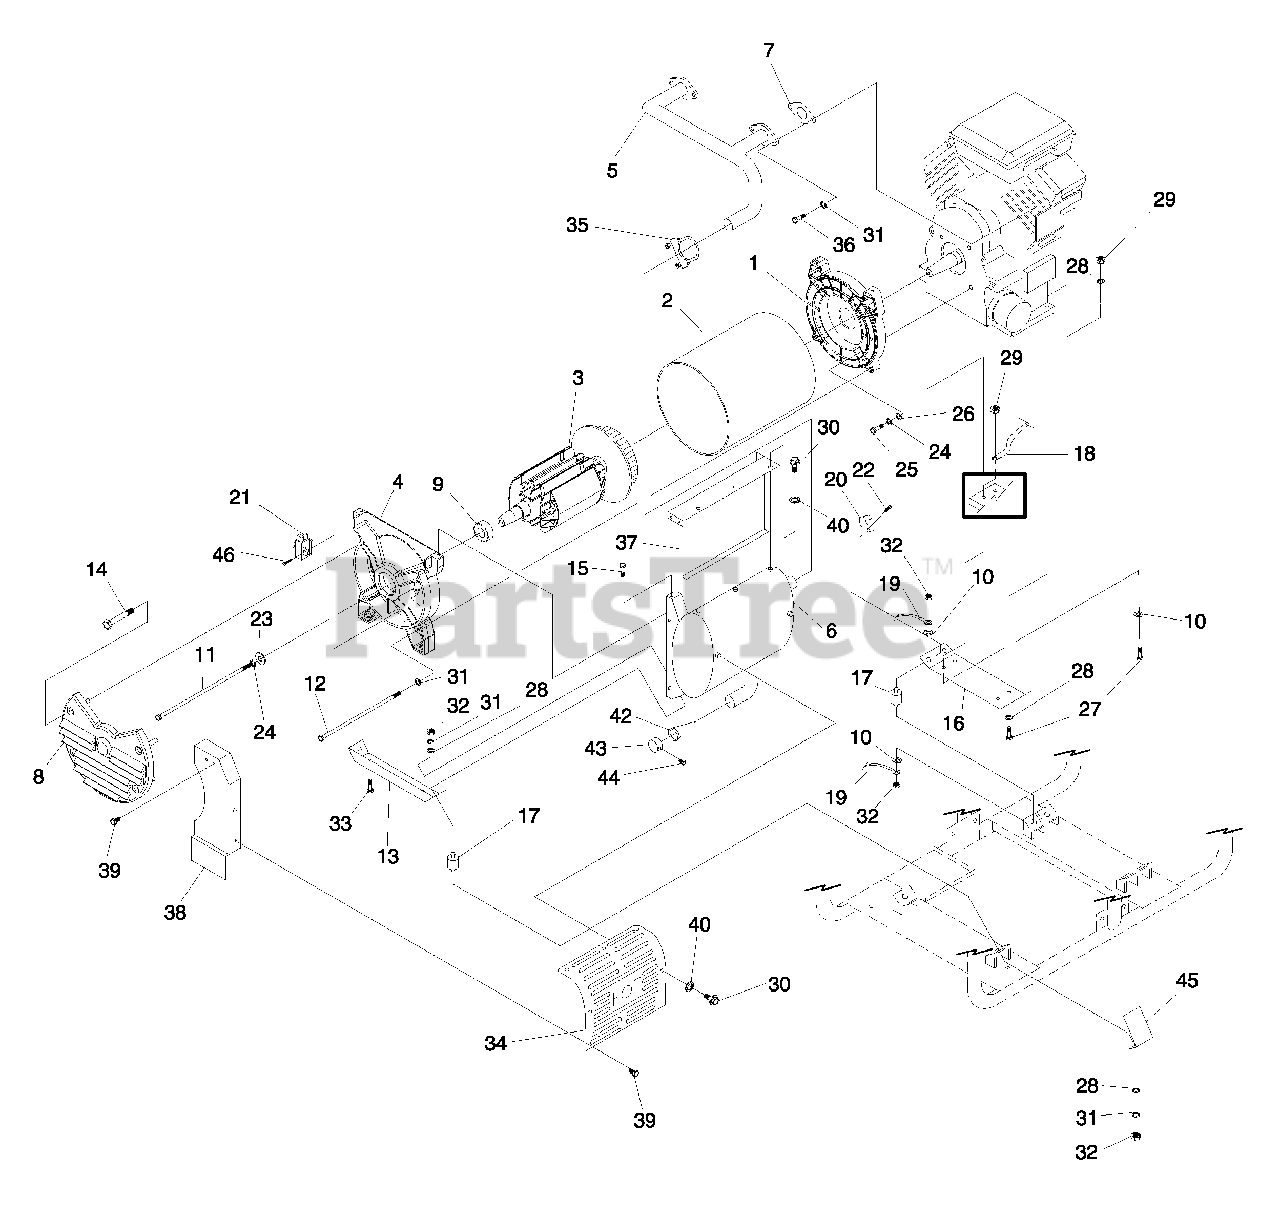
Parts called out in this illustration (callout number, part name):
1	ADAPTOR, ENGINE
2	STATOR 12.5KW
3	ASSEMBLY, ROTOR WITH FAN 12.5KW
4	CARRIER, REAR BEARING
5	EXHAUST MANIFOLD
6	MUFFLER
7	GASKET, EXHAUST
8	COVER, ALTERNATOR AIR IN
9	BEARING
10	5/16 SPECIAL LOCK WASHER
11	SCREW IHHC 3/8-24 X 15.50 G5
12	SCREW IHHC M8-1.25 X 400 G8.8
13	BRACKET, ALT MOUNTING
14	SCREW HHTT #10-32 X 1.75
15	SCREW HHTT M8-1.2 X 20
16	ENGINE MOUNTING PLATE
17	RUBBER MOUNT
18	BATTERY CABLE, BLACK
19	EARTH STRAP 3/8X 3/8
20	CLIP-J VINYL COAT .625 ID
21	ASSEMBLY, BRUSH HOLDER
22	SCREW TAP-R #10-32 X 9/16
23	WASHER FLAT 3/8 ZINC
24	WASHER LOCK 3/8
25	SCREW HHC 3/8-16 X 1-1/4 G5
26	WASHER FLAT 3/8-M10 ZINC
27	SCREW HHC M8-1.25 X 50 G8.8
28	WASHER FLAT 5/16 ZINC
29	NUT LOCK HEX M8-1.25 NYLON INSERT
30	SCREW HHC M6-1.0 X 16 WITH LOCK WASHER
31	WASHER LOCK M8-5/16
32	NUT HEX 5/16-18 STEEL
33	SCREW TAPTITE 3/8-16 X 3/4 BP
34	SHIELD, MUFFLER HEAT
35	U-BOLT & SADDLE
36	SCREW SHC M8-1.25 X 18
37	PANEL, MUFFLER BOX BACK
38	PANEL, MUFFLER BOX END
39	SCREW HHTT M6-1.0 X 12
40	WASHER FLAT 1/4
42	SPARK ARRESTOR SCREEN
43	RETAINER, SPARK ARREST SCREEN
44	SCREW HHTT M4-0.7 X 8
45	SHIELD, RUBBER MOUNT
46	SCREW HHTT M5-0.8 X 16
